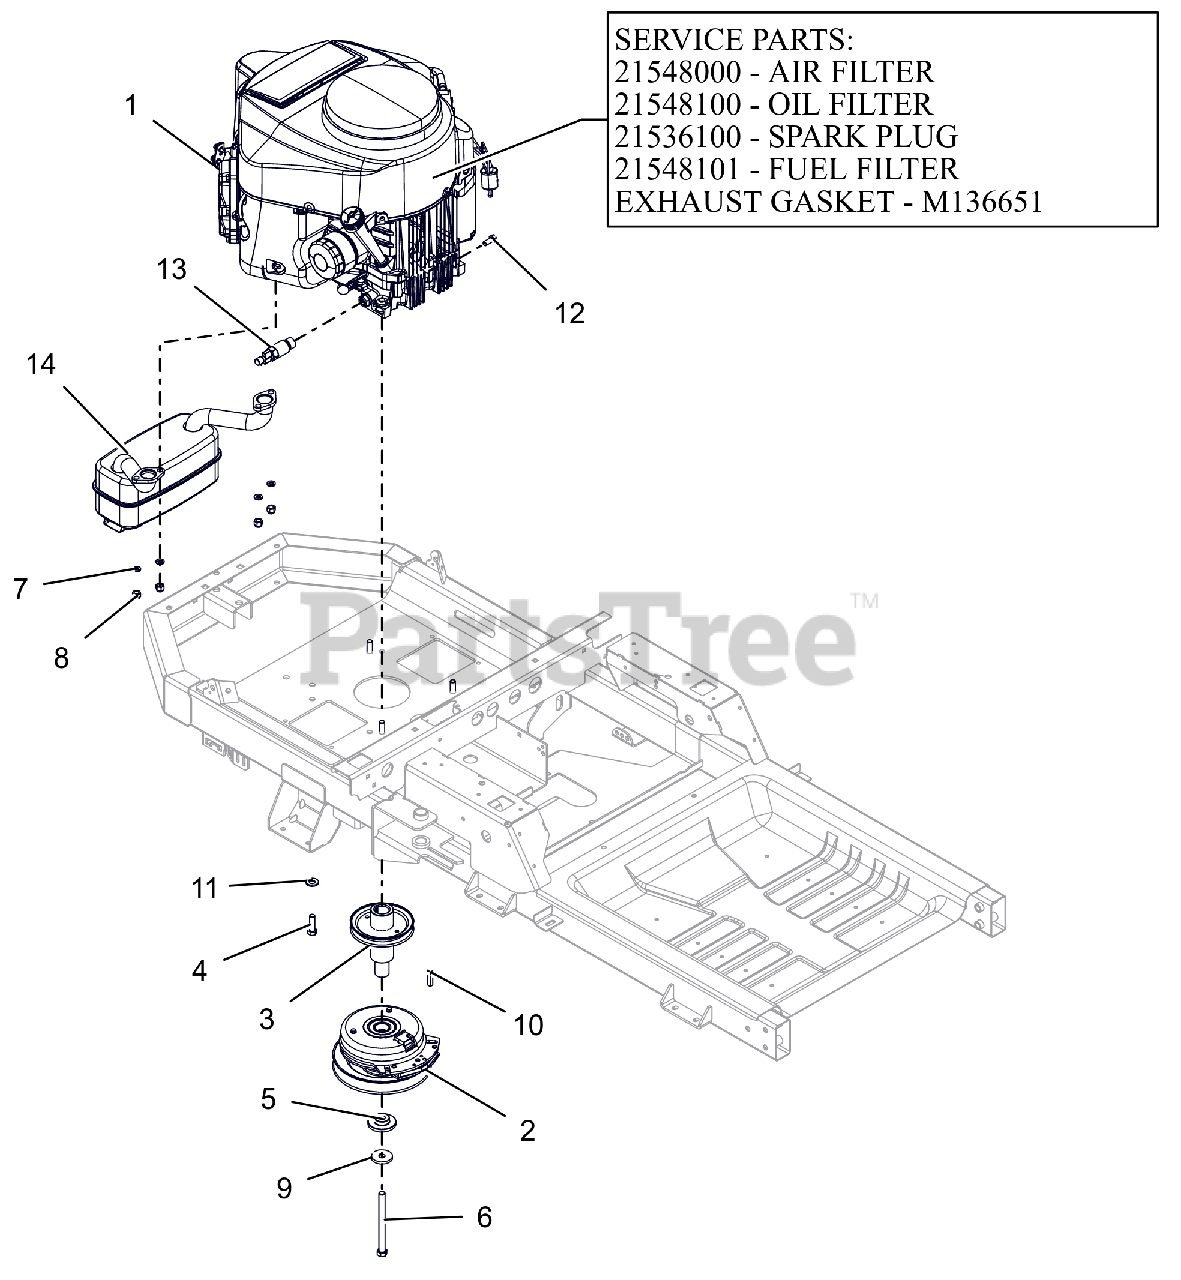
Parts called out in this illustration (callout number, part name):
1	ENGINE, KAWASAKI FR730 24HP
1	AIR FILTER, KAWASAKI FR
1	OIL FILTER, KAWASAKI FR
1	PLUG, SPARK
1	FUEL FILTER-KAWASAKI FR
1	GASKET, MUFFLER #
2	CLUTCH,105FTLB MONOPOLE 6.83"
3	WLDMT, DRIVE SHEAVE (LG XL)CZC
4	BLT, HEX .38-16X1.25 G5 ZCC NT
5	BSHG-FLG .469X1.06X.574X2.0
6	BLT-HEX.438-20X5 GR8 YZ NYTORQ
7	WSHR,LK-REG .312X.078 ZCC
8	NUT,NYL M8-1.25 G8.8 ZCC
9	WASHER, 7/16" SPRING DISK
10	KEY-SQ .25 X 1.25 X .25 SAE
11	WASHER, 3/8" SPRING DISC
12	BLT, HEX M8-1.25X20 G8.8 ZCC
13	DRAIN, OIL M20X2.5
14	MUFFLER - KAWASAKI
